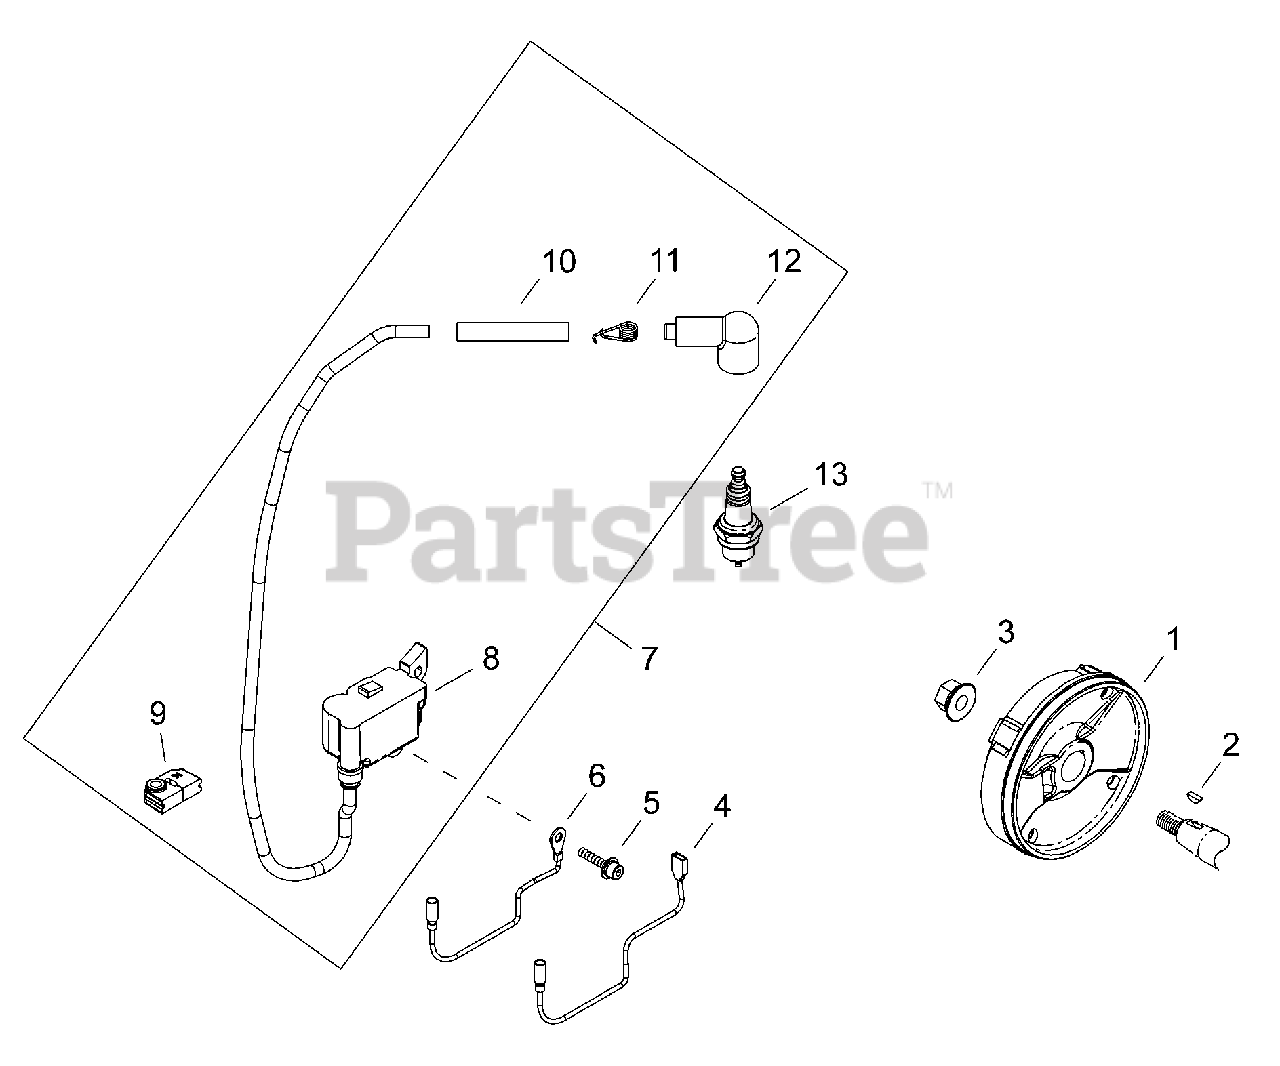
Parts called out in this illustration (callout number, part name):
1	FLYWHEEL
2	KEY - 3X10
3	NUT - 8
4	LEAD - IGNITION
5	SCREW - 4X20
6	LEAD - GROUND
7	IGNITION COIL ASSY
8	COIL, IGNITION
9	GROMMET
10	TUBE
11	TERMINAL, SPARK PLUG CAP
12	CAP, SPARK PLUG
13	SPARK PLUG -- RCJ-6Y
